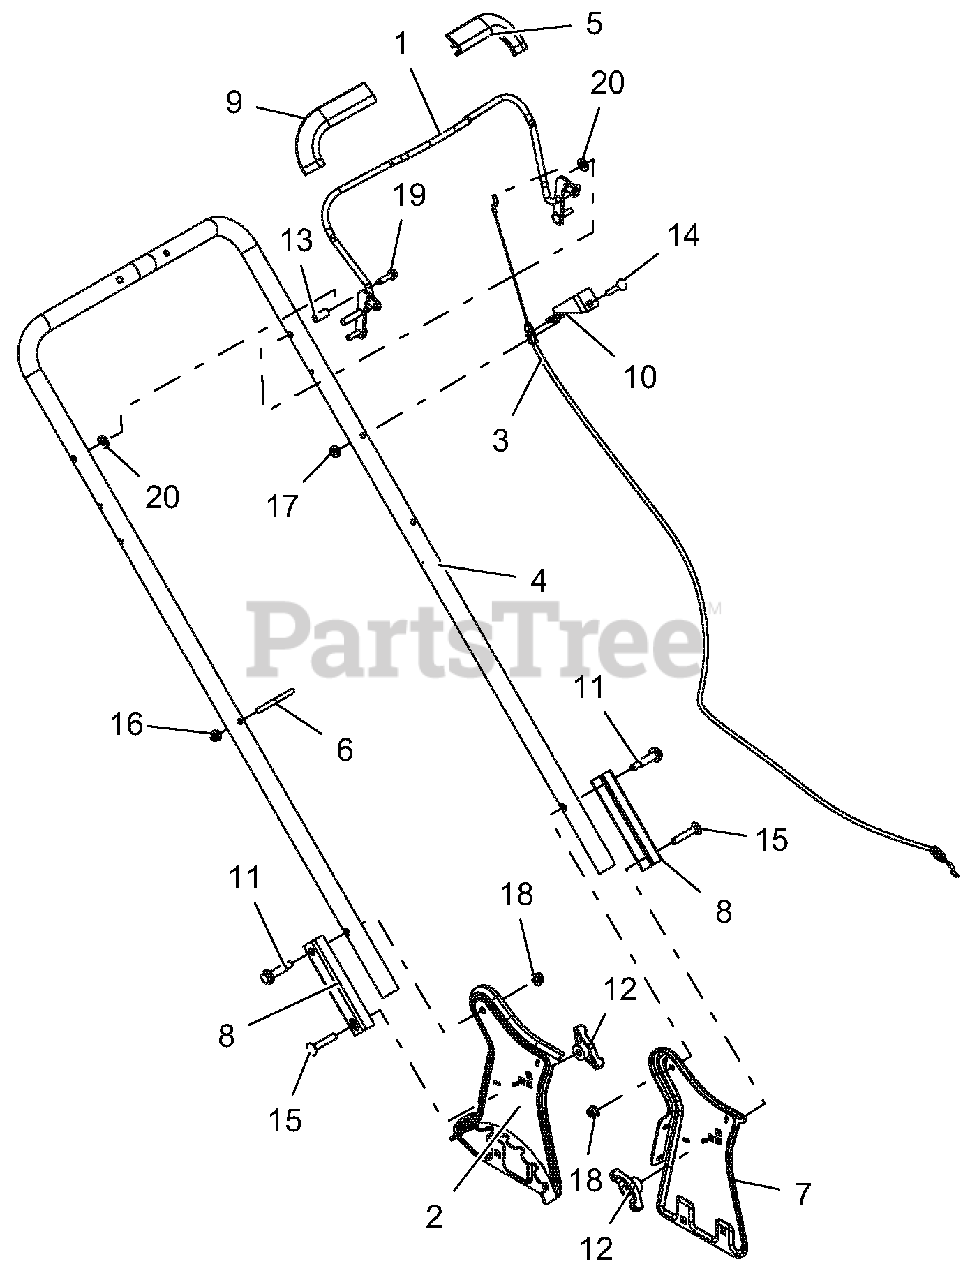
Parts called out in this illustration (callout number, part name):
1	BAIL, OPC
2	WLDMT, RH SIDE PLATE-ARIENS
3	CABLE, OPC
4	HANDLEBAR,
5	GUARD, FINGER - LH
6	GUIDE, RECOIL ROPE
7	SUPPORT, LH HANDLEBAR
8	BRKT, HANDLEBAR FIXED ADJUST
9	GUARD, FINGER - RH
10	BRKT, CABLE ANCHOR - LM PUSH
11	BLT, SHLDR .50X1.30X.38-16 GR5
12	KNOB, WING .31-18 UNC NYL/TALC
13	CAP, VINYL
14	BLT-RDHDSQNK .25-20X1.50 G5 Y
15	BLT-RDHDSQNK .31-18X1.75 G5 YWZC
16	NUT-LK-NYL-FLG .25-20 YWZC
17	NUT, LK-TOP-FLG .25-20 YWZC
18	NUT, LK-TOP-FLG .312-18 YWZC
19	SCR-TAP .25-20X1.00 HWH TR YZ
20	WSHR-FL-STL.344X.688X.065YWZC
